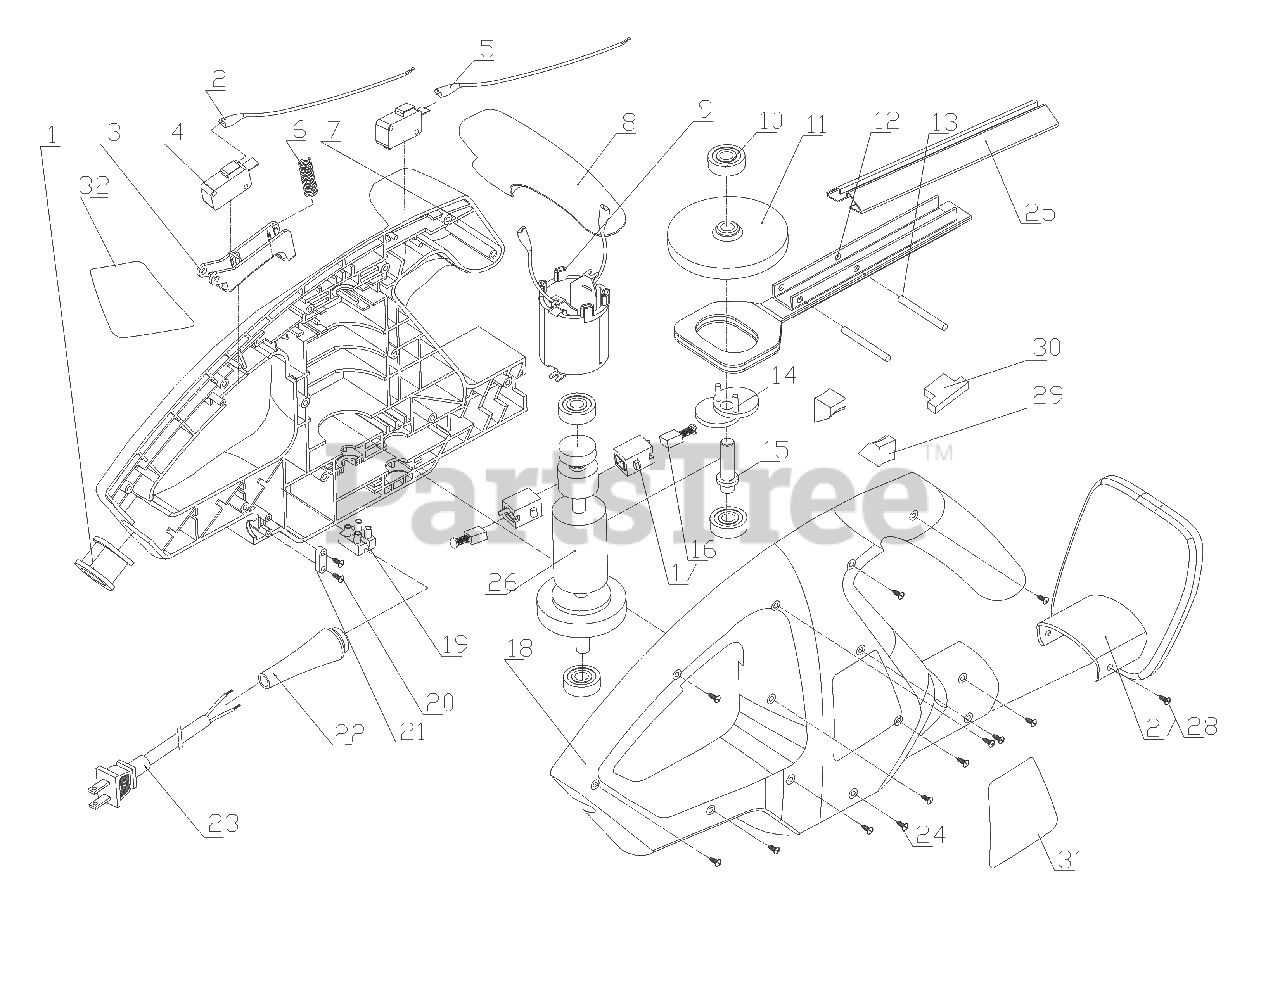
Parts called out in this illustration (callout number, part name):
1	TUBE
2	WIRE
3	TRIGGER
4	SWITCH
5	WIRE
6	SPRING
7	HOUSING (L)
8	TRIGGER
9	FIELD ASS'Y
10	BEARING
11	GEAR
12	16" BLADE
13	PIN
14	ECCENTRIC SHAFT
15	OUTPUT SHAFT
16	BRUSH
17	BRUSH HOLDER
18	HOUSING (R)
19	TERMINAL BLOCK
20	SCREW
21	STRAIN RELIEF
22	CORD GUARD
23	POWER CORD
24	SCREW
25	BLADE COVER
26	ARMATURE
27	COVER
28	SCREW
29	GASKET
30	GASKET
31	LABEL (R)
32	LABEL (L)
